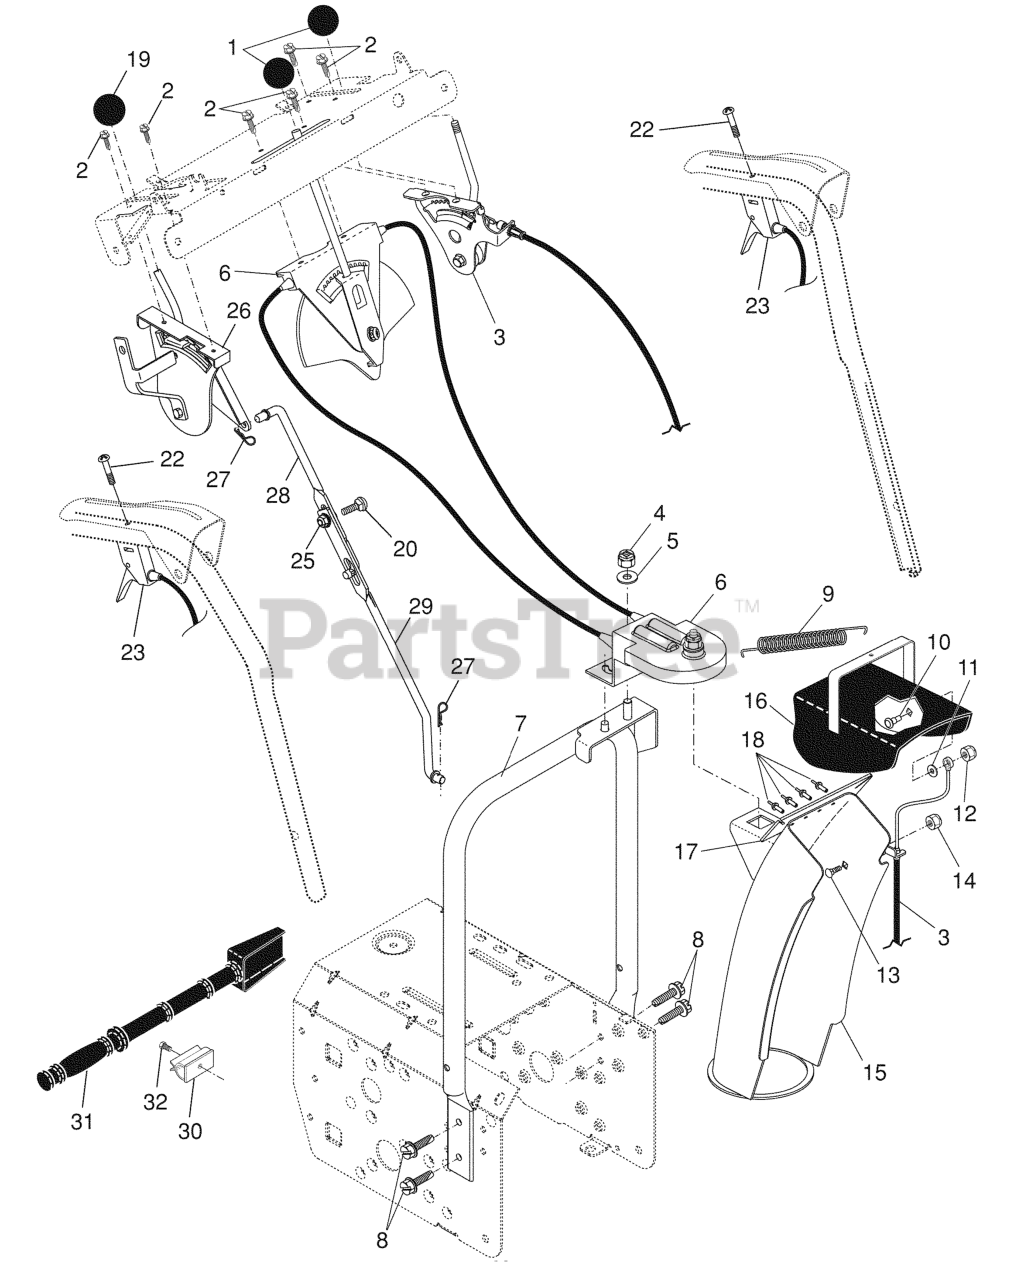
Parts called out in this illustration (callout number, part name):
1	KNOB LEVER, BLACK
2	SCREW #10-24 X 5/8
3	CONTROL.CABLE.DEFLECTOR
4	NUT
5	WASHER
6	CONTROL ASSEMBLY,CHUTE ROTATER
7	SUPPORT, PIVOT
8	SELF-TAPPING SCREW 5/16-18X3/4
9	SPRING.DEFLECTOR.REM.CHUTE
10	BOLT, SHOULDER
11	WASHER, NYLON FRICTION
12	NUT.HEX.FLANGE.1/4
13	BOLT
14	NUT.LOCK.5/16-18
15	CHUTE ASSEMBLY
16	DEFLECTOR.WELDMENT.PNT.ORANGE
17	SEAL, DEFLECTOR
18	RIVET BLIND
19	RED KNOB SHIFTER
20	BOLT
23	STEERING.CONTROL.SNOW.BLUE
25	NUT.FLANGE.5/16
26	HEAD ASSY SPEED
27	SPRING RETAINER
28	ROD, UPPER SPEED CONTROL
29	ROD, LOWER SPEED CONTROL.SNOW
30	CLIP.CLEANOUT.TOOL
31	CLEAN OUT TOOL
32	SCREW.HWH.13-16-5.8.BZP
